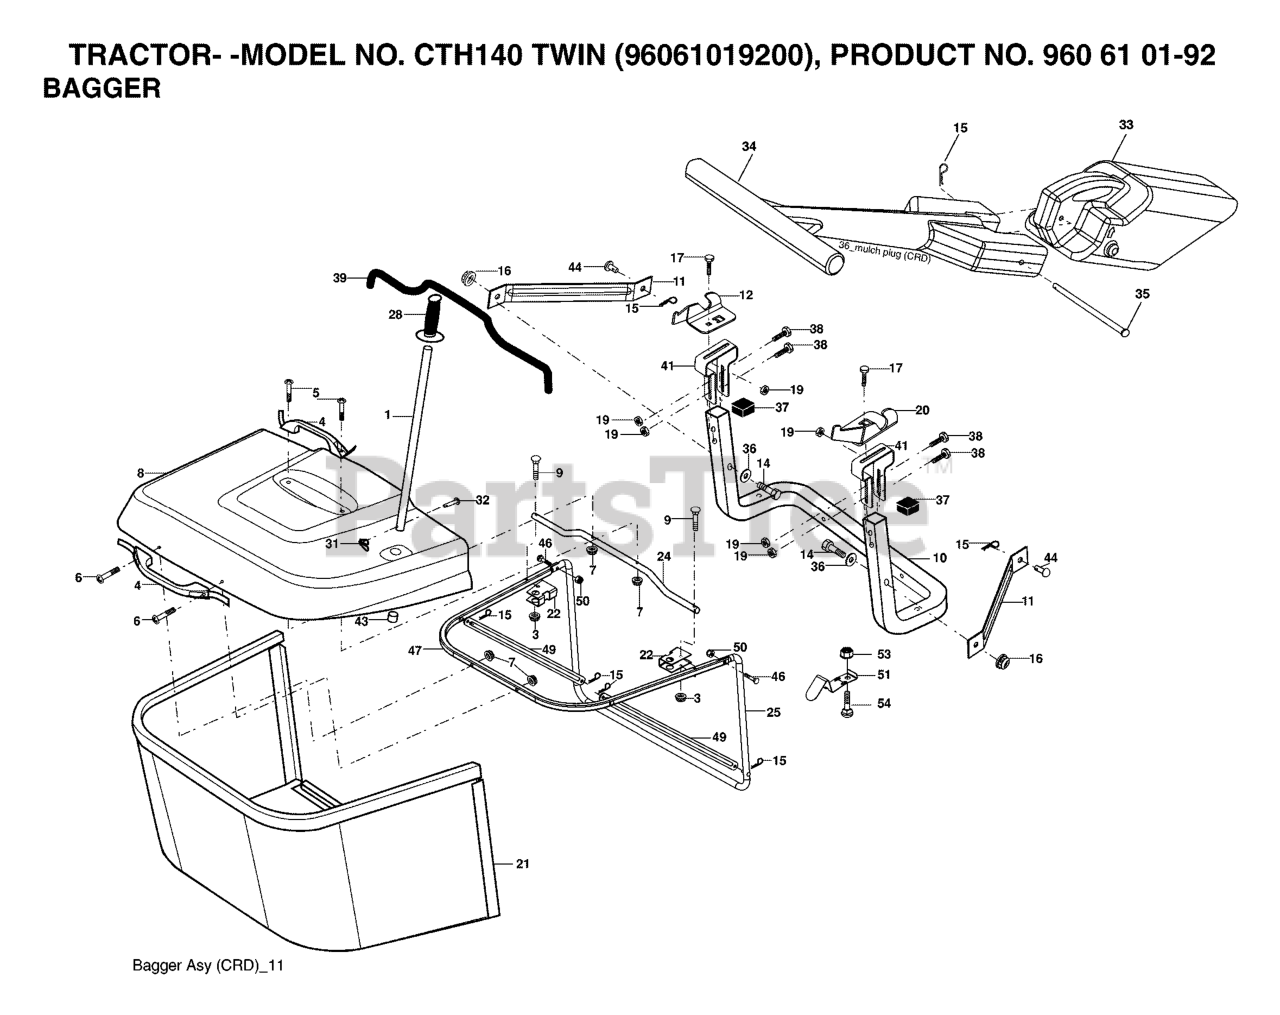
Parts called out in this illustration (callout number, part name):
1	TUBE HANDLE
3	NUT T
4	HANDLE.BAGGER.W/LVRS.BLK.CRD
5	SCREW.PAN.HEAD
6	REPL BY 532 75 00-29
8	COVER.PNT.BGR.CRD.WSLOTS.MS668
9	Bolt Carriage 1/4-20 x 2.25d x Gr.5
10	TUBE
11	BRACKET.SUPPORT.UPPER.BAG.CRD
12	BRKT PIVOT
14	BOLT-HEX EAK
15	RETAINER-SPRNG RB
16	NUT LOCK FLG 3/8-16 UNC
17	RP BOLT 5/16-18 X3/4 ZN/YEL GR
19	NUT LOCK HEX FLANGE 5/16-18
20	BRKT.PIVOT.RH.CRD
21	BAGGER.ASM.CRD.2007
22	BRKT.SIDE.BAG.CRD
24	TUBE.PIVOT.BAG.CRD.BLACK
25	PIPE
28	GRIP.HANDLE.BLACK
31	RETAINER CLIP
32	RIVET,DRILLED
33	PLUG.MULCHER.92 CRD
34	HANDLE.MULCHER.92.CRD (2 2)
36	WASHER
37	Plug Support Bagger CRD
38	BOLT.5/16-18X2.5
39	SEAL.TRIM.37'
41	BRKT.VERT.ADJ.BAGGER.CRD
43	PLUG, TUBING END
46	BOLT.CARRIAGE.5/16-18
47	PIPE
49	ROD
50	NUT.71038.31-18.HEX.NYLOCK
51	LATCH
53	NUT
54	BOLT
